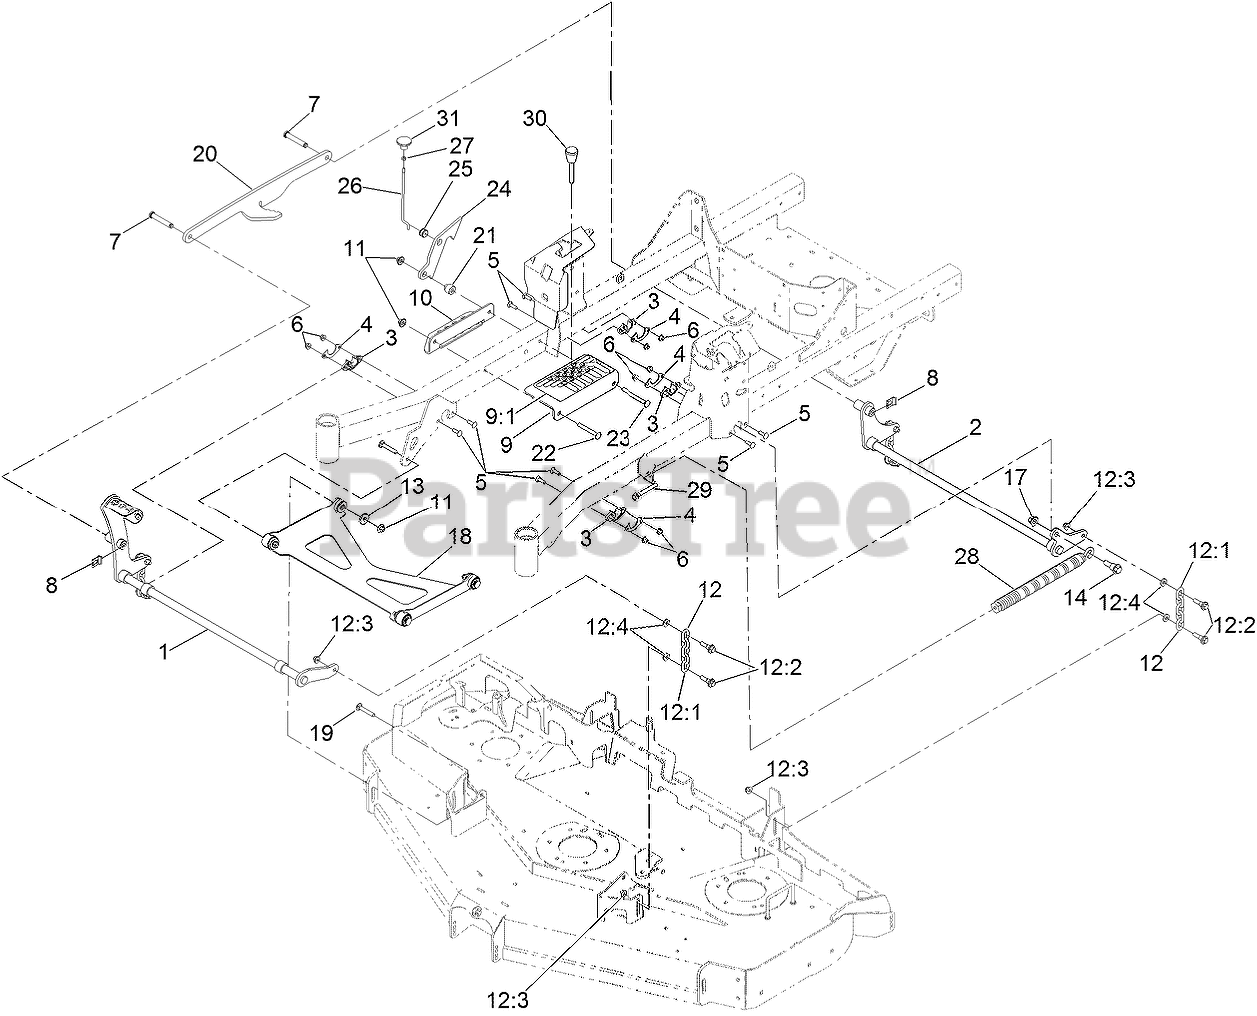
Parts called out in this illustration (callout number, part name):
1	SHAFT-LIFT, DECK
2	SHAFT-LIFT, DECK (REAR)
3	BUSHING-FLANGE
4	GUSSET-LIFT, DECK
5	SCREW-CARR
6	NUT-HF, NI
7	PIN-CLEVIS
8	CLIP-PIN
9	BRACKET ASM
9:1	DECAL-HOC
10	ANGLE-HOC, LOWER
11	Nut-Nyloc 3/8-16 Flg
12	DECK CHAIN ASM
12:1	CHAIN-LIFT, DECK
12:2	BOLT-SHOULDER
12:3	NUT-HF, NI
14	SCREW-SHOULDER, HHF 1/2-13 X 1.12
17	Nut-Lock 1/2-13
18	DECK STRUT ASM
19	Bolt-Carriage 3/8-16 X 2 1/4
20	LINK-LIFT
21	SPACER-STEPPED
22	SCREW-CARR
23	SCREW-CARR
24	PLATE-LOCK, TRANSPORT
25	GROMMET
26	ROD-LOCK, TRANSPORT
27	NUT-JAM
28	SPRING-EXTENSION
29	BOLT-SHOULDER
30	PIN-HOC
